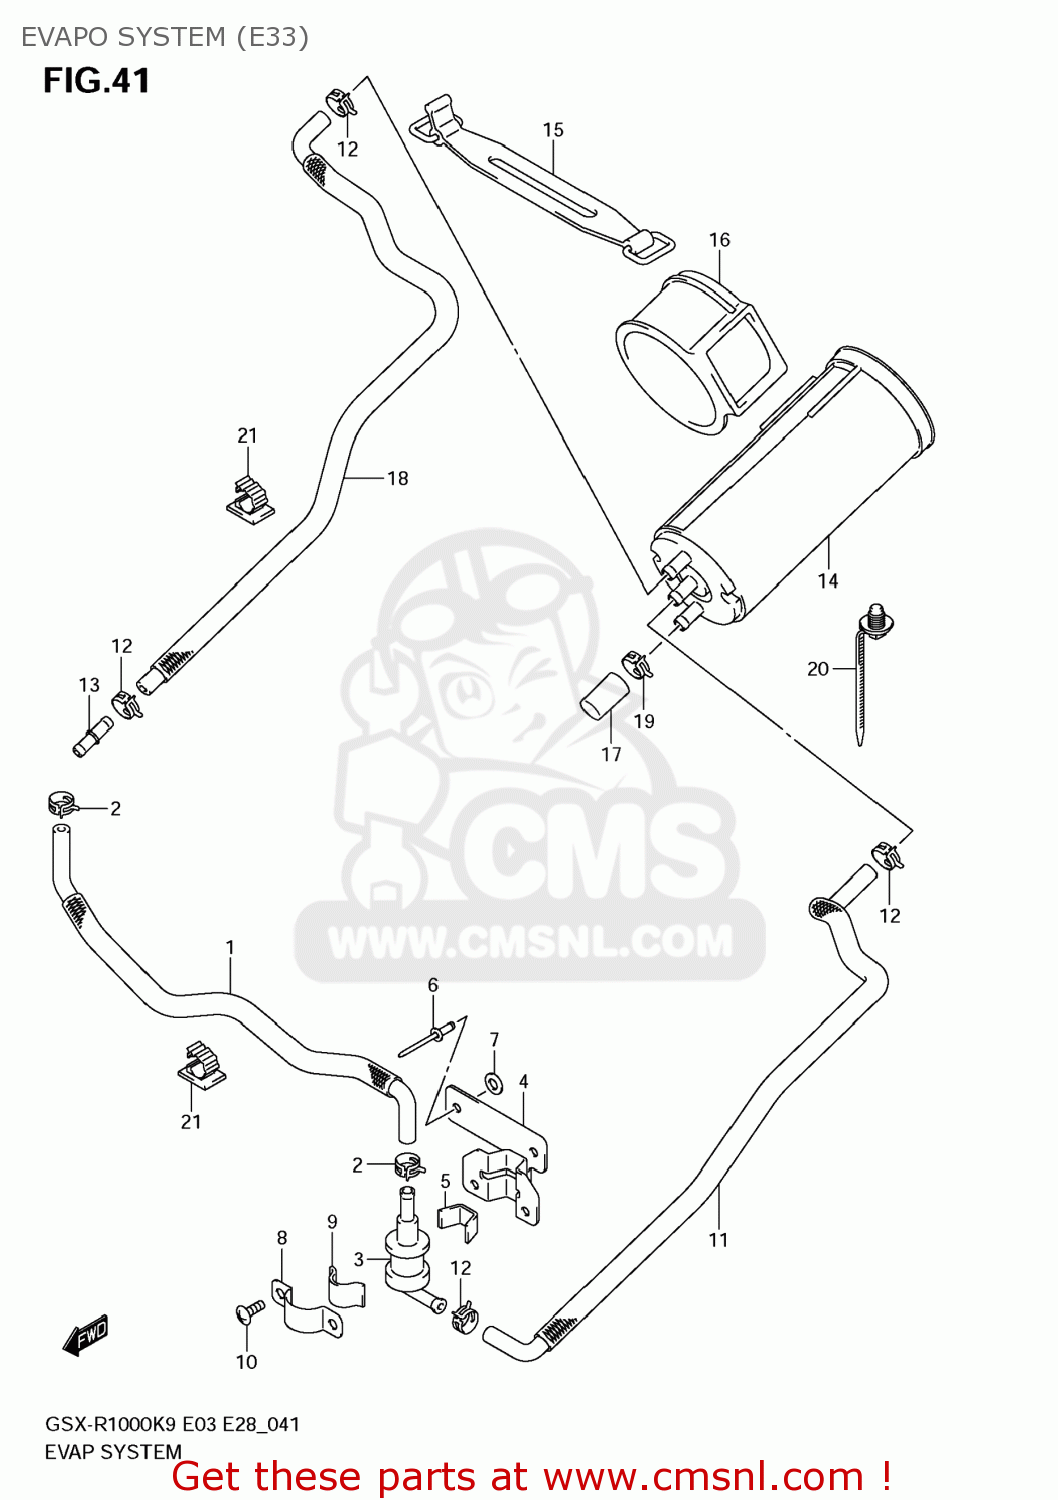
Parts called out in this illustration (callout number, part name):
1	HOSE,TANK & BREATHER VALVE
2	CLIP
3	VALVE,FUEL TANK BREATHER
4	PLATE,BREATHER VALVE
5	CUSHION
6	RIVET
7	WASHER
8	PLATE,FUEL TANK BREATHER NO.2
9	CUSHION
10	SCREW
11	HOSE,CSTR & BREATHER VALVE
12	CLIP
13	JOINT
14	CANISTER ASSY,CHARCOAL
15	BAND,CANISTER
16	CUSHION,CANISTER
17	CAP,OD:11.5
18	HOSE,CSTR PURGE
19	CLIP
20	CLAMP(L:154)
21	CLAMP
